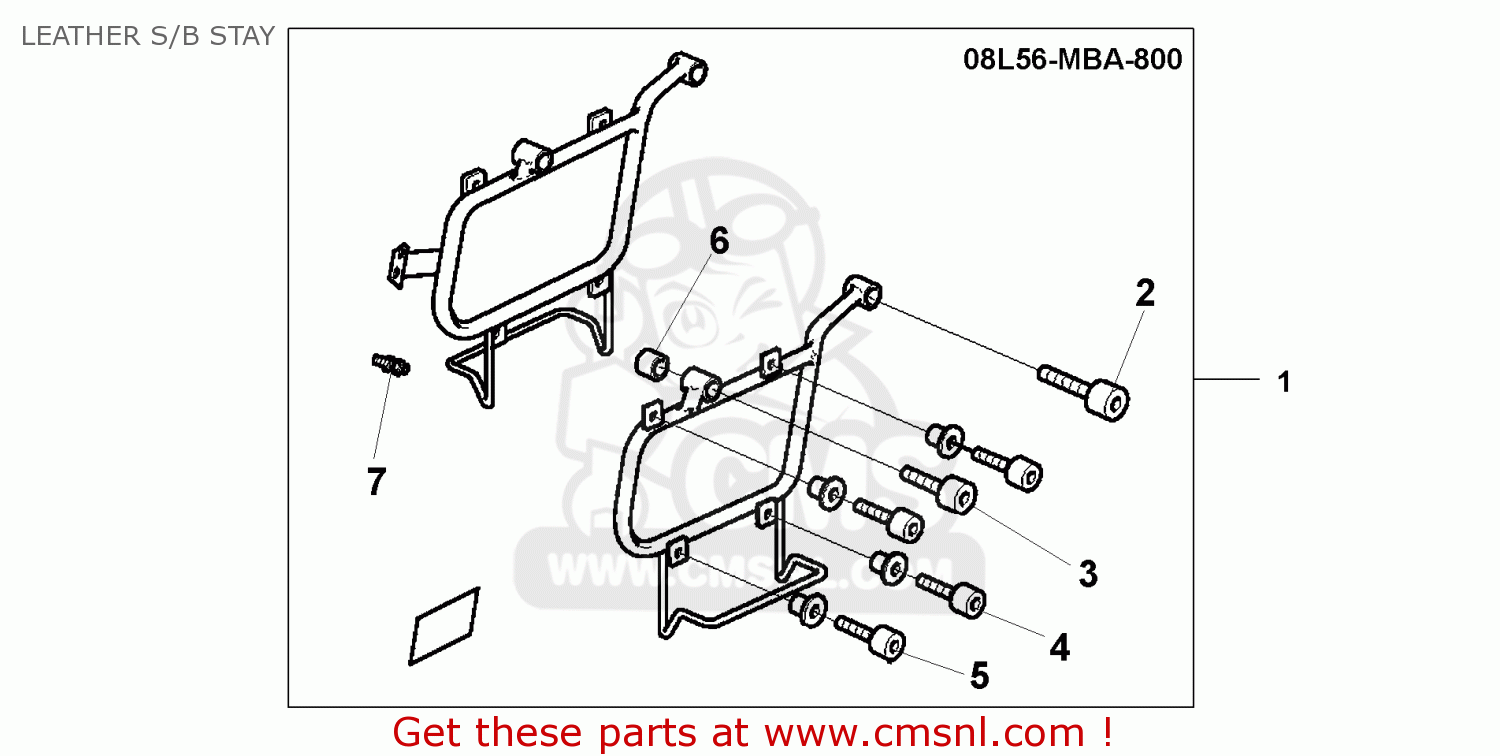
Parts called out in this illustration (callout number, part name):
1	LEATHER S/B STAY
2	SOCKET.BOLT,10X35
3	BOLT,SOCKET,8X55
4	SOCKET BOLT,6X12
5	WASHER,6X20
6	WASHER 9X20X6
7	BOLT,HELMET.HOLD.
